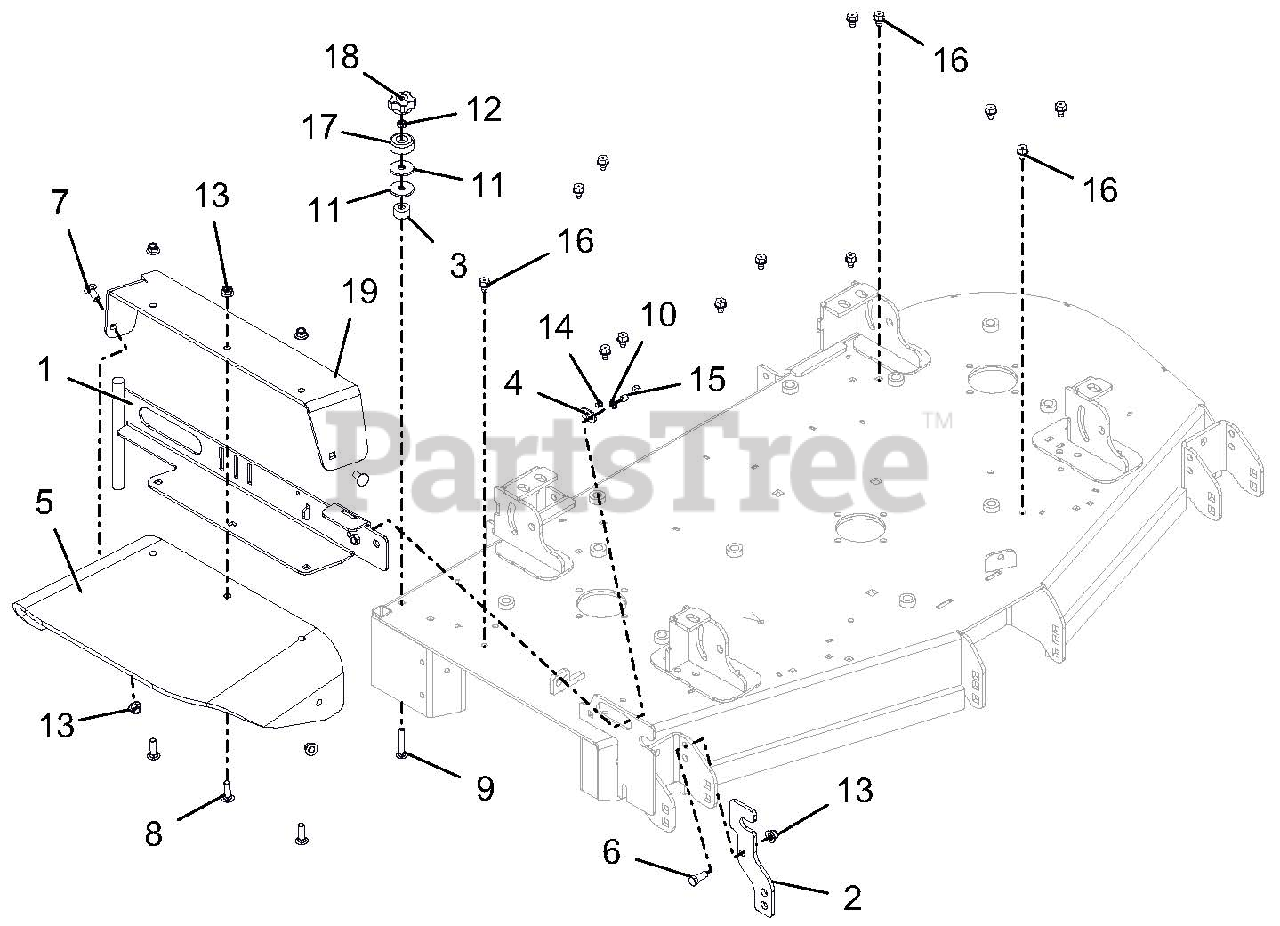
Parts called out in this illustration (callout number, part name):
1	WLDMT, 52" DISCHARGE CHUTE MTG-CE
2	CHUTE STORAGE BRACKET - RED
3	SPACER .390X1.000X.562
4	KEEPER, BOLT
5	CHUTE, RUBBER DISCHARGE
6	@BLT-HEX .38-16X1.00 GR5 YWZC
7	@BLT-RDHDSQNK .38-16X1.00 G5YZ
8	@BLT-RDHDSQNK .38-16X1.25 G5YZ
9	BLT-RDHDSQNKFT .31-18X2.0 G5YZ
10	@WSHR-LK-EXT.391X.628X.036YWZC
11	WSHR-FL-STL .380X1.50X.125YWZC
12	@NUT-LK-CTR .31-18 YWZC
13	@NUT-LK-NYL-FLG .38-16 YWZC
14	RVT-POP .187x.250 (#64) YWZC
15	BLT-HEX .38-16X1.25 GR5 CAP .37
16	@SCR-TAP .38-16X.50 HWH TR YWZ
17	BUMPER,RECESSED1.50X.63 W/.31
18	KNOB-CLAMPING, .312-18 NYLOC
19	DISCH CHUTE SUPPORT W/DECAL
